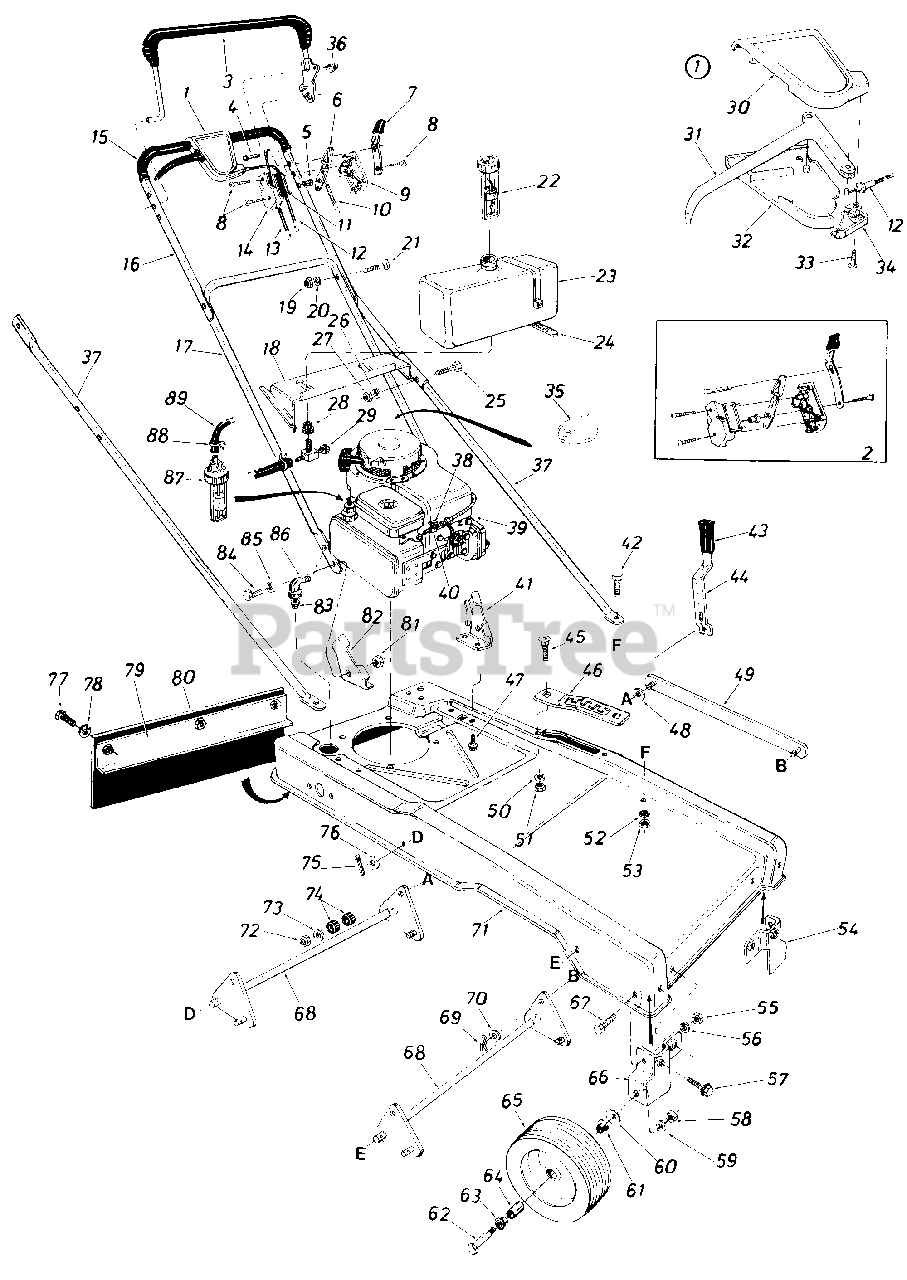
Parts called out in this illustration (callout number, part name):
1	Clutch Control Housing Comp.
2	Control Housing Comp.
3	Control Handle Ass'y.
4	Lock Pin
5	Control Disc Pin
6	Throttle Control Lever
7	Spring Lever Knob
8	Truss Mach. Hi-B Tap Scr. #12 x 1.50" Lg.
9	Control Panel Half
10	Throttle Control Wire 43" Lg. Yellow
11	Control Label-Throttle
12	Drive Clutch Cable-46" Lg.
13	Self-Propelled Cable 50" Lg.
14	Clutch Panel Half
15	Grip 22" Lg.
16	Upper Handle
17	Lower Handle
18	Gas Tank Mounting Brk't.
19	Hex Nut 5/16-18 Thd.
20	L-Wash. 5/16" I.D.
21	Carriage Bolt 5/16-18 x 1.50" Lg.
22	Gas Gauge 13/4-6 x 5.50" Lg.
23	Gas Tank
24	Cable Tie 30.6" Lg.
25	Hex Bolt 5/16-24 x 1.25" Lg.*
26	L-Wash. 5/16" I.D.
27	Hex Nut 5/16-24 Thd.
28	Bushing-Gas Tank
29	Fuel Shut-Off Valve w/Screen
30	Control Cover Half-Upper
31	Control Lever
32	Control Cover Half-Lower
33	Flat "C" Sunk Hd. Tap Scr. #10 x .75" Lg.
34	Cable Mounting Cap
35	Cable Tie
36	Push Cap
37	Strut .75" O.D. x 43.44" Lg.
38	Hex Sems Scr. #10-32 x .62" Lg.
39	Engine-5 H.P.
40	Casing Clamp
41	Handle Mount Brk't.-L.H.
42	Hex Bolt 5/16-18 x .75" Lg.
43	Grip-Black
44	Lift Handle
45	Carriage Bolt 5/16-18 x .62" Lg.*
46	Lift Handle Support Brk't.
47	Hex Wash. Hd. B-Tap Scr. 5/1 6-1 8 x .50
48	Fl-Wash. .406" I.D. x 1.25" O.D.
49	Connecting Link Ass'y.
50	L-Wash. 5/16" I.D.
51	Hex Nut 5/16-18 Thd.
52	L-Wash. 5/16" I.D.
53	Hex Nut 5/16-18 Thd.
54	Wheel Brk't. Ass'y.-L.H.
55	Hex Nut 5/16-18 Thd.
56	L-Wash. 5/16" I.D.
57	Hex Sems Bolt 5/16-18 x .75" Lg.
58	Hex Cent. L-Nut 3/8-16 Thd.
59	L-Wash. 3/8" I.D.
60	Bell-Wash. .400" I.D. x .88" O.D.
61	Flange Ball Brg. .501" I.D.
62	Hex Bolt 3/8-16 x 2.00" Lg.
63	Flanged Ball Brg. 3/8" I.C) .
64	Spacer .375" I.D. x .505" O.D. x 1" Lg.
65	Wheel Ass'y. Comp. 8 x 1.75
66	Wheel Brk't. Ass'y.-R.H.
67	Hex Sems Bolt 5/16-18 x .75" Lg.
68	Lift Brk't. Shaft Ass'y.
69	Intern. Cotter Pin 5/16" Dia.
70	Fl-Wash. .385" I.D. x .88" O.D.
71	Hi-Wheel Frame
72	Hex Ins. L-Nut 3/8-24 Thd.
73	Fl-Wash. .385" I.D. x .87" O.D.
74	Rubber Wash. .33" I.D. x .87" O.D.
75	Cotter Pin 1/8" Dia. x 1" Lg.*
76	Fl-Wash. .510" I.D. x 1.0" O.D.
77	Hex Bolt 1/4-20 x .62" Lg.
78	L-Wash. 1/4" I.D.
79	Retaining Strip Ass'y. 2" x 15" Lg.
80	Rear Flap 7.5 x 20" Lg.
81	Hex Nut 3/8-16 Thd.
82	Handle Mount Brk't.
83	Part of Engine
84	Hex Bolt 3/8-16 x .75" Lg.
85	L-Wash. 3/8" I.D.
86	90 Deg. Elbow Male to Female 3/8
87	Fuel Control Valve
88	Hose Clamp-.406" Dia.
89	Fuel Line 13" Lg.
